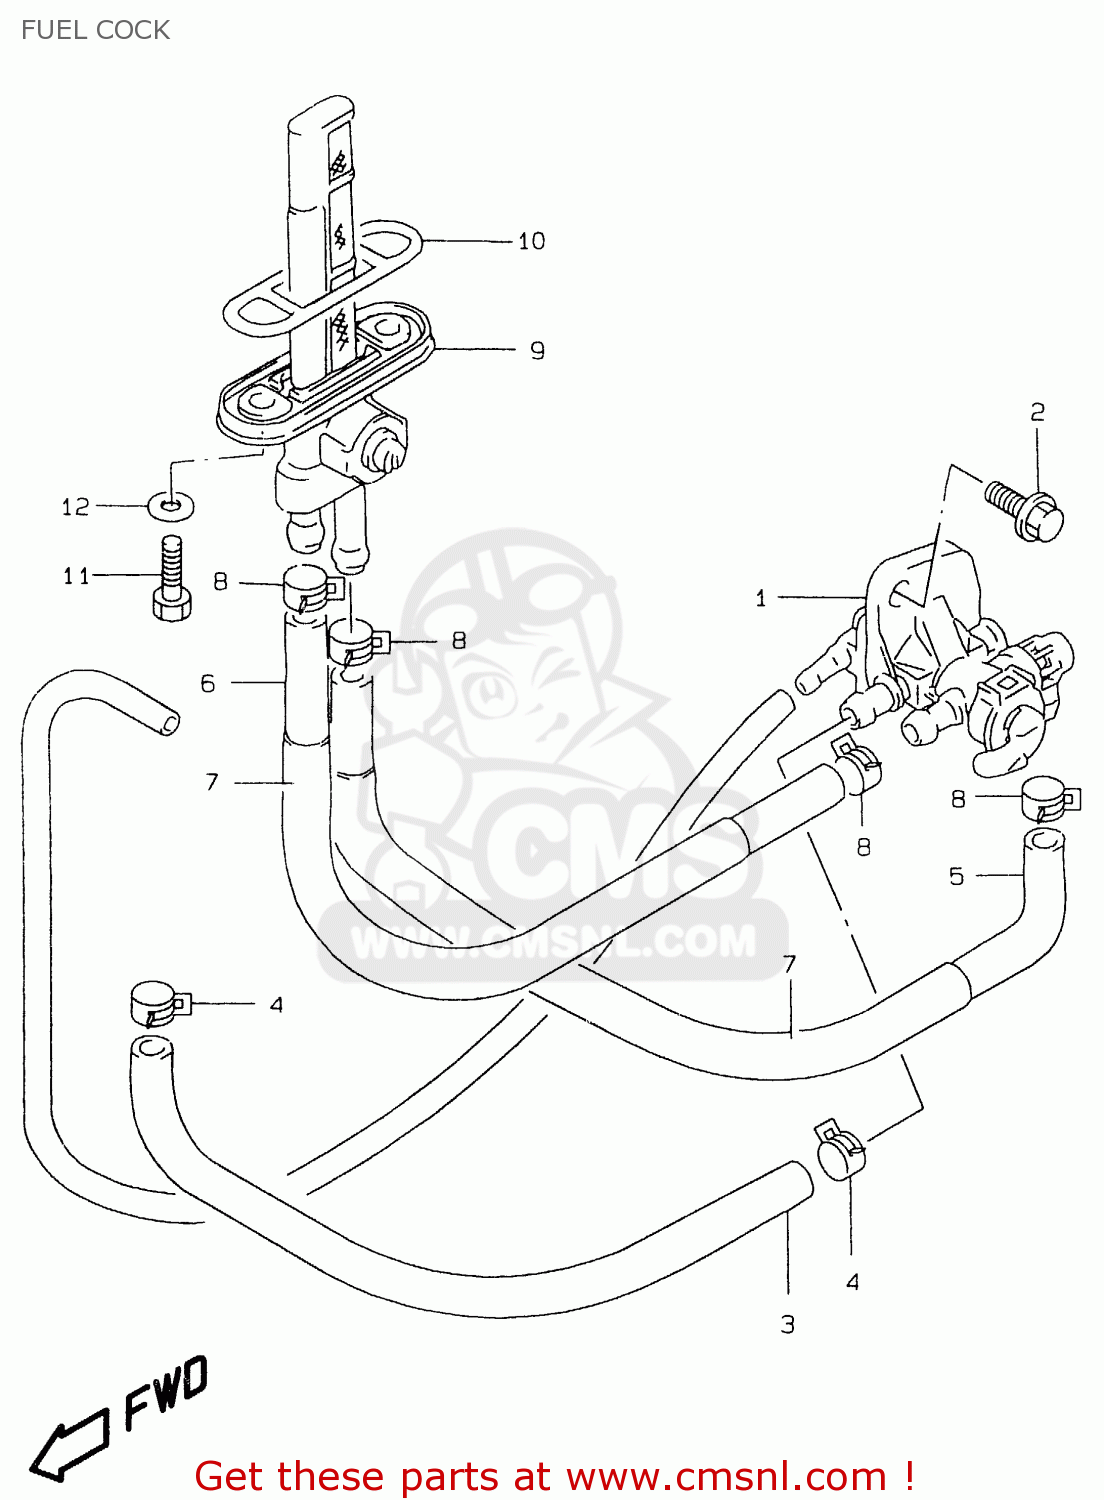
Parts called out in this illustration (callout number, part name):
1	COCK ASSY,FUEL
2	BOLT
3	HOSE
4	CLIP
5	HOSE
6	HOSE,FUEL RESERVE
7	PROTECTOR,FUEL HOSE
8	CLIP
9	COCK ASSY,FUEL NO.1
10	O RING,FUEL COCK
11	BOLT(6X20)
12	GASKET(6.4X11.5X0.8) (NAS)
